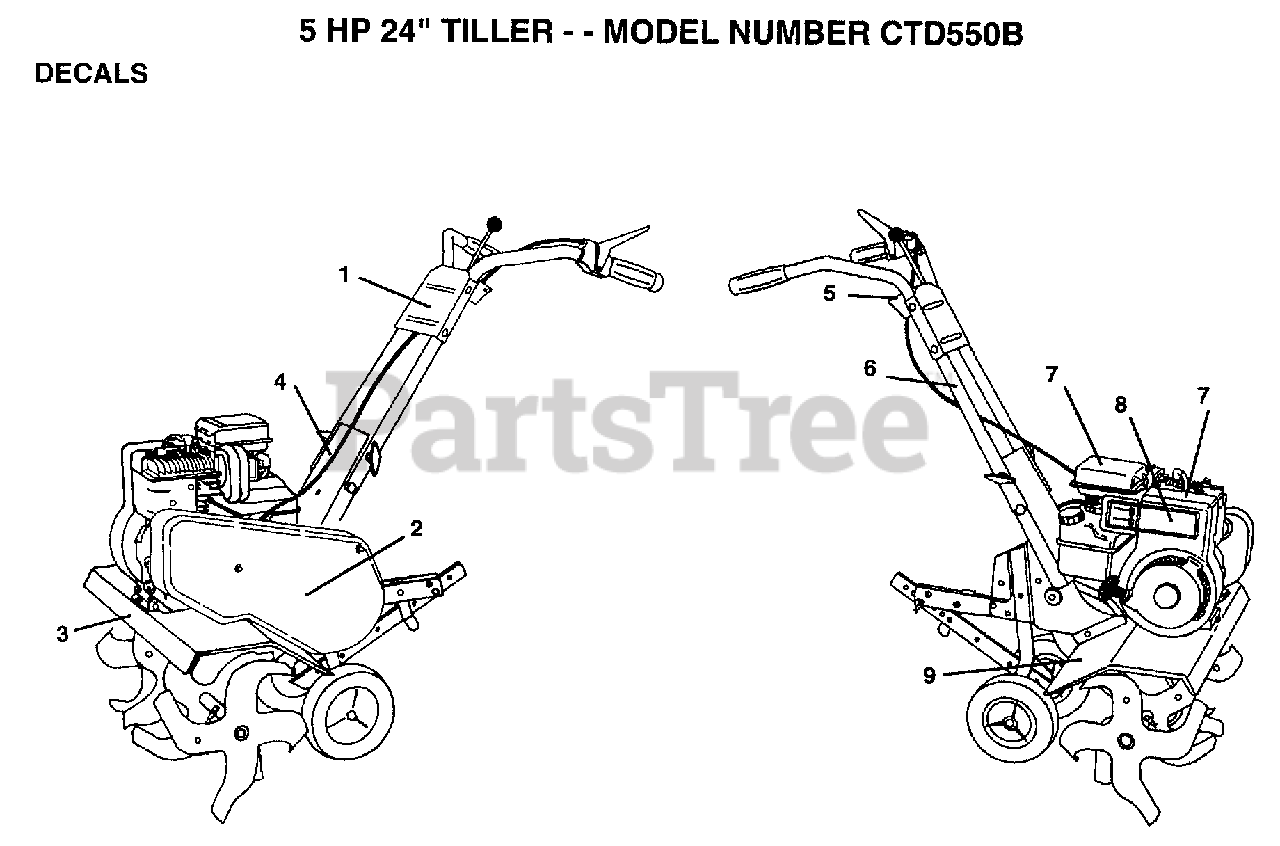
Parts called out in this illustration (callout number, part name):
1	DECAL PNL CNTL
2	DECAL GUARD BELT
3	DECAL TINE SHIELD
5	DECAL REVERSE
6	DECAL TI
9	DECAL TI
